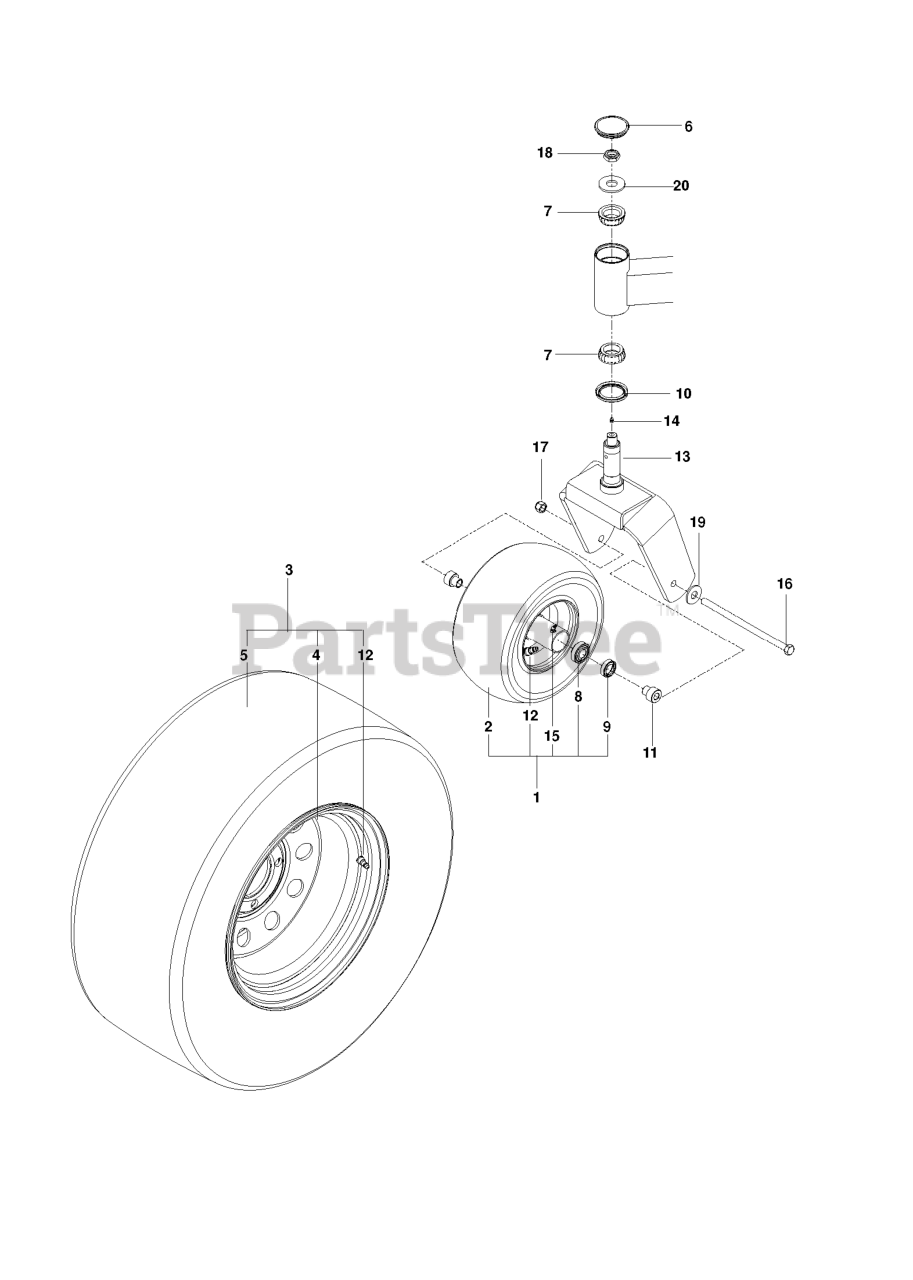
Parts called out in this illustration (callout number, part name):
1	FRONT TIRE ASSY
2	TIRE - SMOOTH 13X6.50-6
3	WHEEL/TIRE.ASM SILV 23X10.5-12
4	RIM, 12 X 8.5, 1.125" NEG OS
5	TIRE.TURF.MASTER.23X10.5-12
7	CONE, LM67048
8	TAPERED BEARING W/RACE
10	SEAL, BEARING
11	AXLE SPACER
12	VALVE STEM TR-412
13	FORK.CASTER.ORANGE
15	ZERK
16	HEX SCREW 1/2-13 X 9.5 GR5
17	NUT, 1/2-13 HEX FLG NYLOC ZD
18	NUT, 3/4-16 HEX THIN NYLOC ZD
19	WASHER 1/2" FLAT
20	WASHER, 3/4 HARDENED
